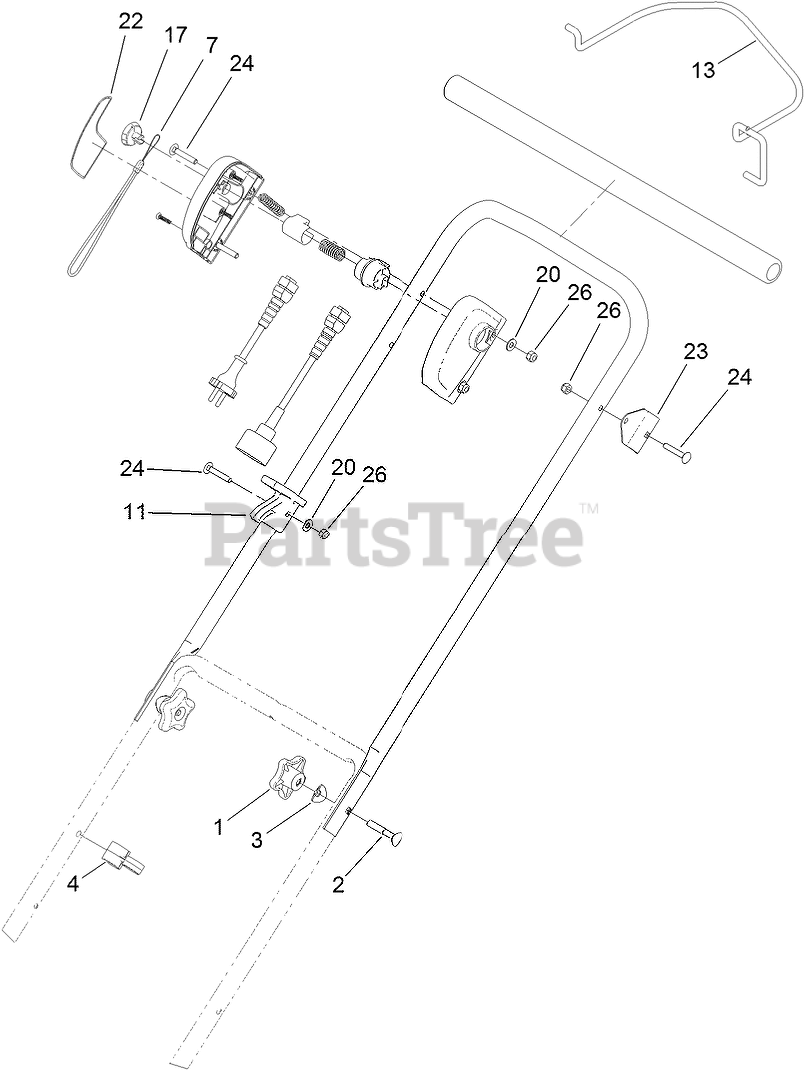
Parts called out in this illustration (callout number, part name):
1	KNOB-HANDLE
2	SCREW-HANDLE
3	WASHER-CUP
4	GUIDE-CABLE
7	CORD-KEY
11	LOCK-CORD
17	KEY-BAIL
20	WASHER-PLAIN
22	DECAL-OPERATION
23	BRACKET-BAIL
24	BOLT-CARR
26	NUT-HEX
